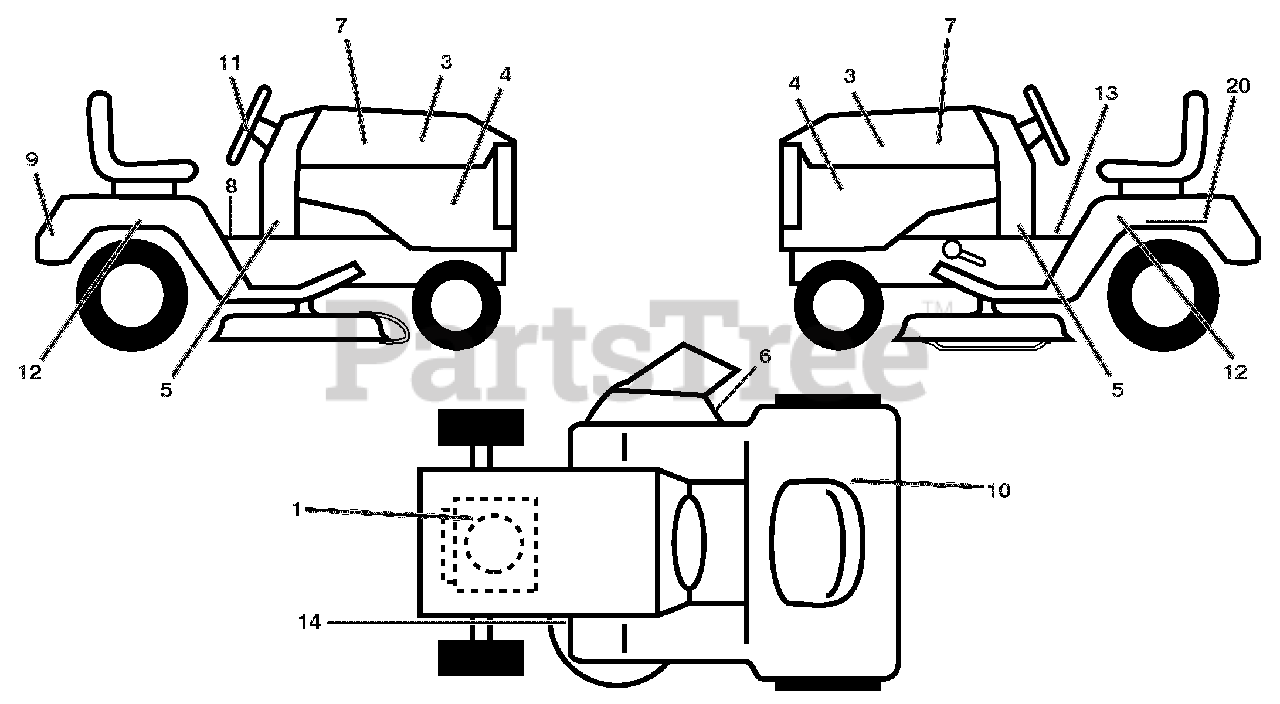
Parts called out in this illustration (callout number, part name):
1	DECAL ENGINE H.P.
3	DECAL.HOOD.LH/RH.
4	DECAL.SDPNL.PWRDBY B&S.ARIENS
5	DECAL.DASH.LWOWER.20HP.ARIENS
6	DECAL.MOWER.WARN.KEEP HAND AWY
7	DECAL.REPLACEMENT
8	DECAL.FENDER.WARNING.ENG/FR.07
9	DECAL.FENDER.REAR.ARIENS
10	LABEL EPA COMPLIANCE
11	DECAL.WHEEL.STEER.ARIENS
12	DECAL.FENDER.SIDE.HYDRO.ARIENS
13	DECAL.FENDER
14	DECAL.V-BELT.SCH.42/46"MEC/ELE
20	DECAL.BAT.DAN/POI P/L SYM.WPN
